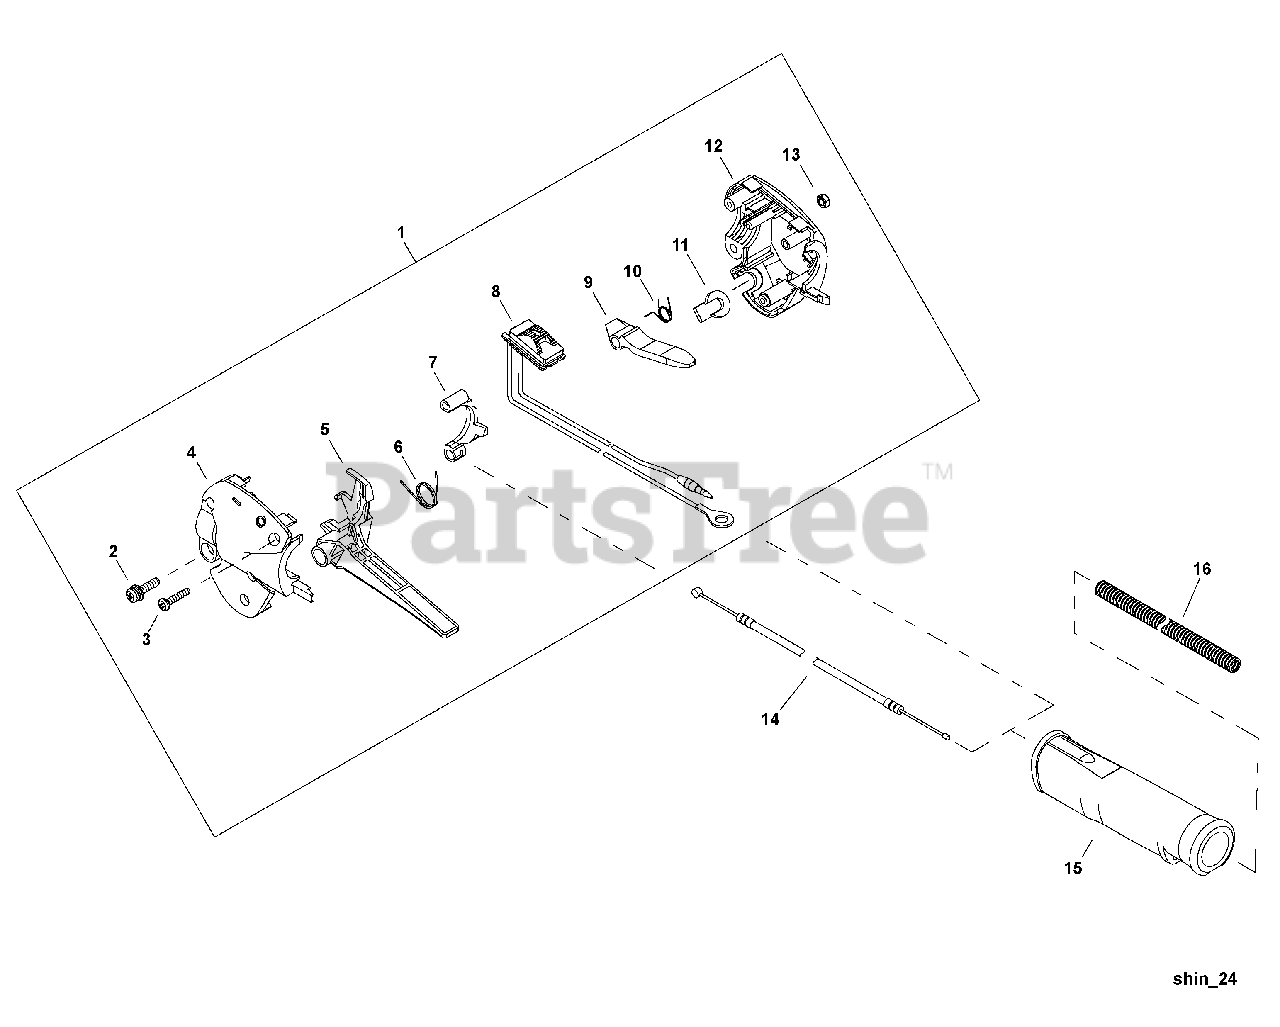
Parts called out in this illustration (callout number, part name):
1	THROTTLE CONTROL ASSY
2	SCREW M5×20
3	SCREW, TAPPING M4×20
4	CONTROL HANDLE - LEFT
5	TRIGGER, THROTTLE
6	SPRING, THROTTLE RETURN
7	LOCKOUT, THROTTLE
8	SWITCH, ON-OFF
9	LEVER, THROTTLE LOCKOUT
10	SPRING, THROTTLE LOCKOUT
11	PLUG
12	CONTROL HANDLE - RIGHT
13	NUT M5
14	CABLE, THROTTLE
16	TUBE, PLASTIC PROTECTIVE
